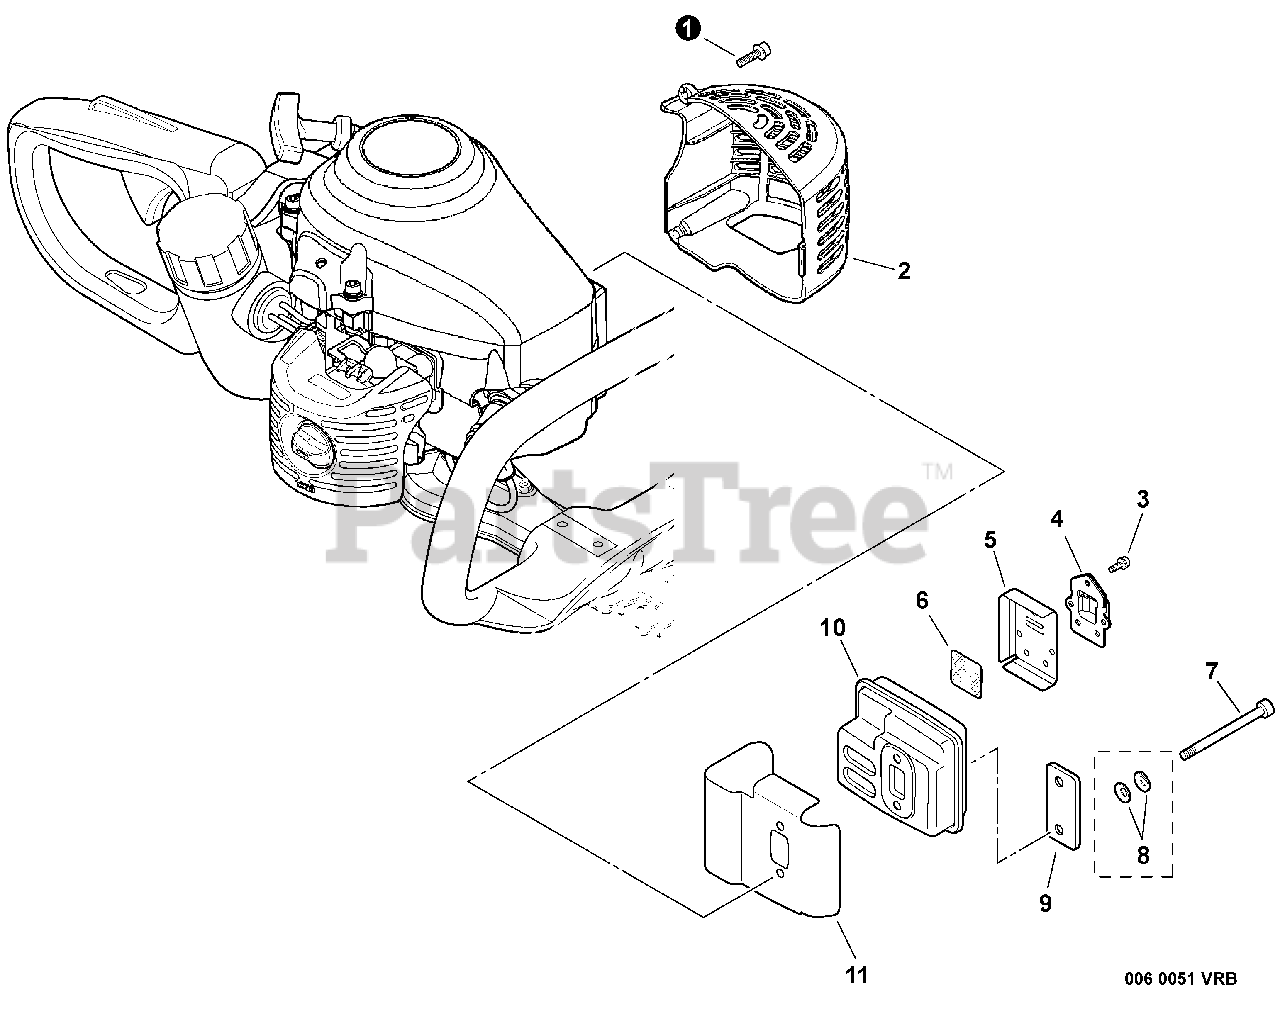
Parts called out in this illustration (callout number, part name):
1	BOLT 5×16
2	COVER, MUFFLER
3	SCREW 4×10
4	GUIDE, EXHAUST
5	GASKET, EXHAUST
6	SCREEN, SPARK ARRESTER
7	BOLT 5×55
8	CONICAL WASHER
9	PLATE, EYE
10	MUFFLER
11	HEAT SHIELD, EXHAUST
